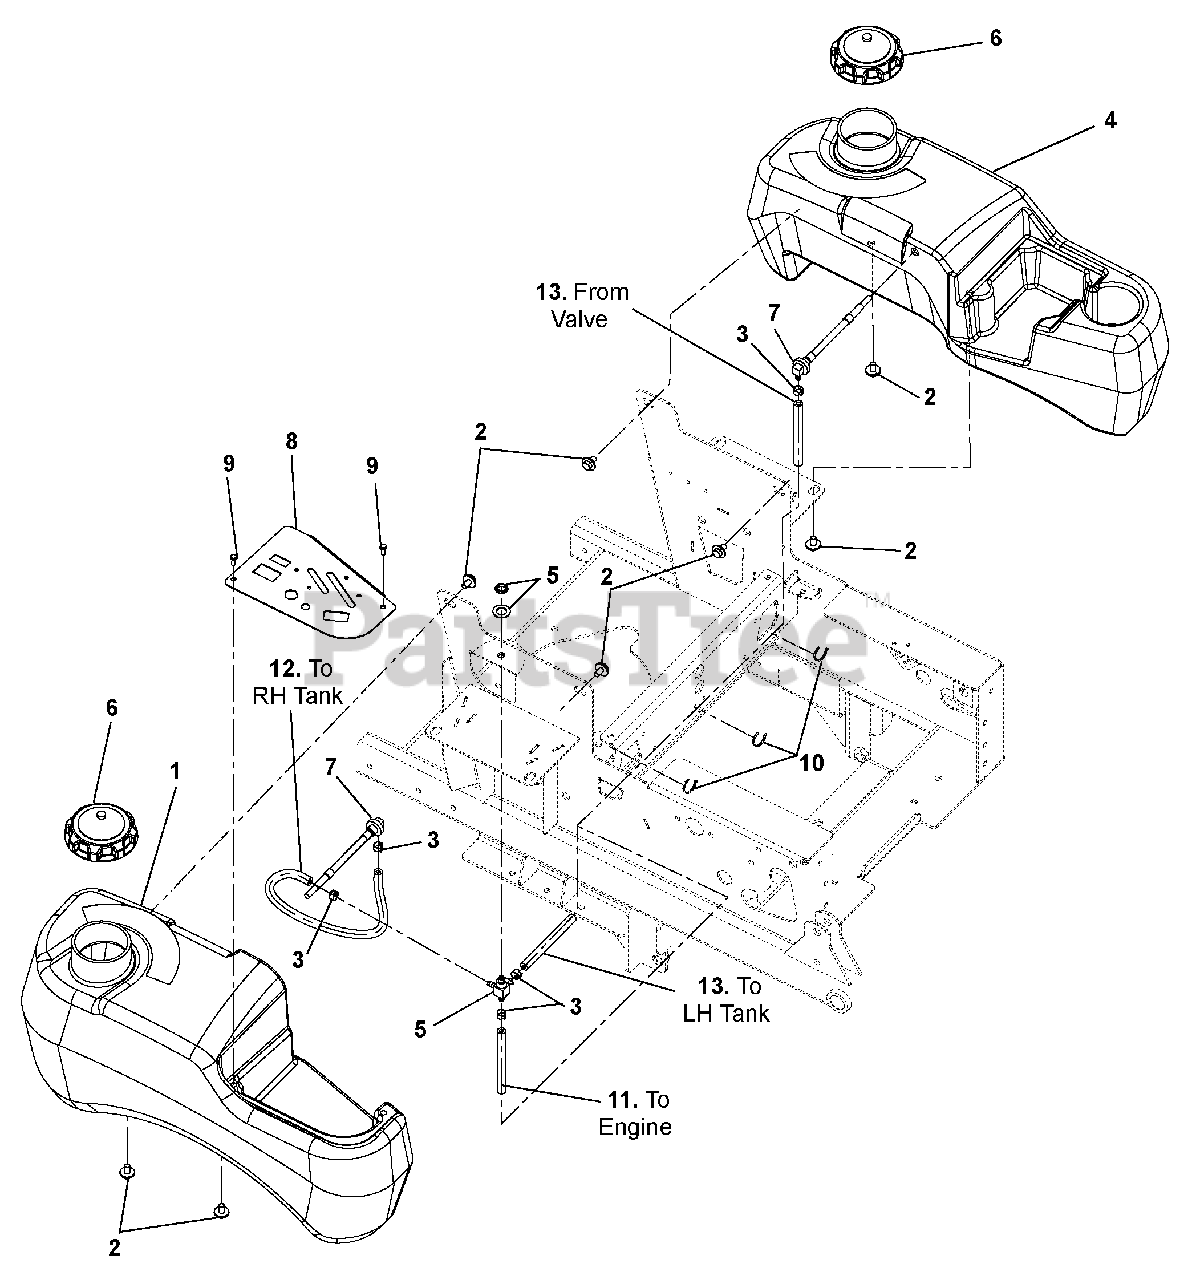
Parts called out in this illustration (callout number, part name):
1	Tank, Right Hand Fuel
2	Bolt, SEMS .31-18 x .62
3	Clamp, Fuel Line
4	Tank, Left Hand Fuel
5	Valve, Fuel
6	Cap, Fuel
7	Assembly, Medium Tank Fuel Pick-up
8	Panel, Control
9	Screw, Machine 10-24 x .50
10	Cable Tie
11	Hose, .25 Low-PERM Bulk Gas
12	Hose, .25 Low-PERM Bulk Gas
13	Hose, .25 Low-PERM Bulk Gas
